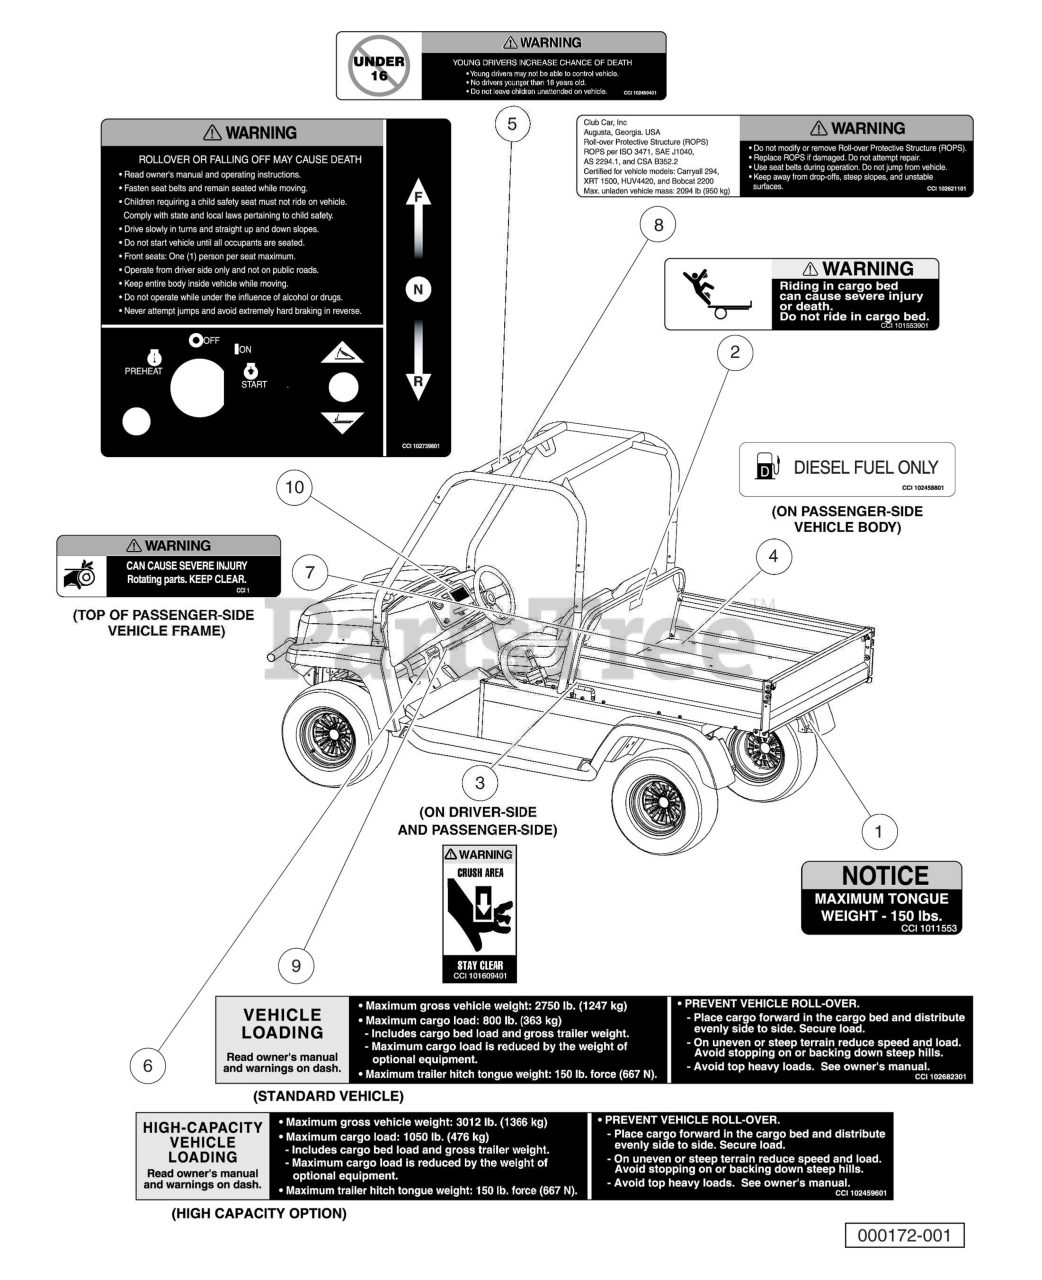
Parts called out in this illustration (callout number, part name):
1	Decal, Trailer Hitch
2	Decal, Bed Load Warning
3	Decal, Crush Area Warning
4	Decal, Diesel Fuel Only
5	Decal, Young Driver Warning
6	Decal, Vehicle Loading, High-Capacity
7	Decal, Rotating Parts Warning
8	Decal, ROPS Certification/Warning
9	Decal, Vehicle Loading, Standard Capacity
10	Decal, Warning, Diesel Instrument Panel
